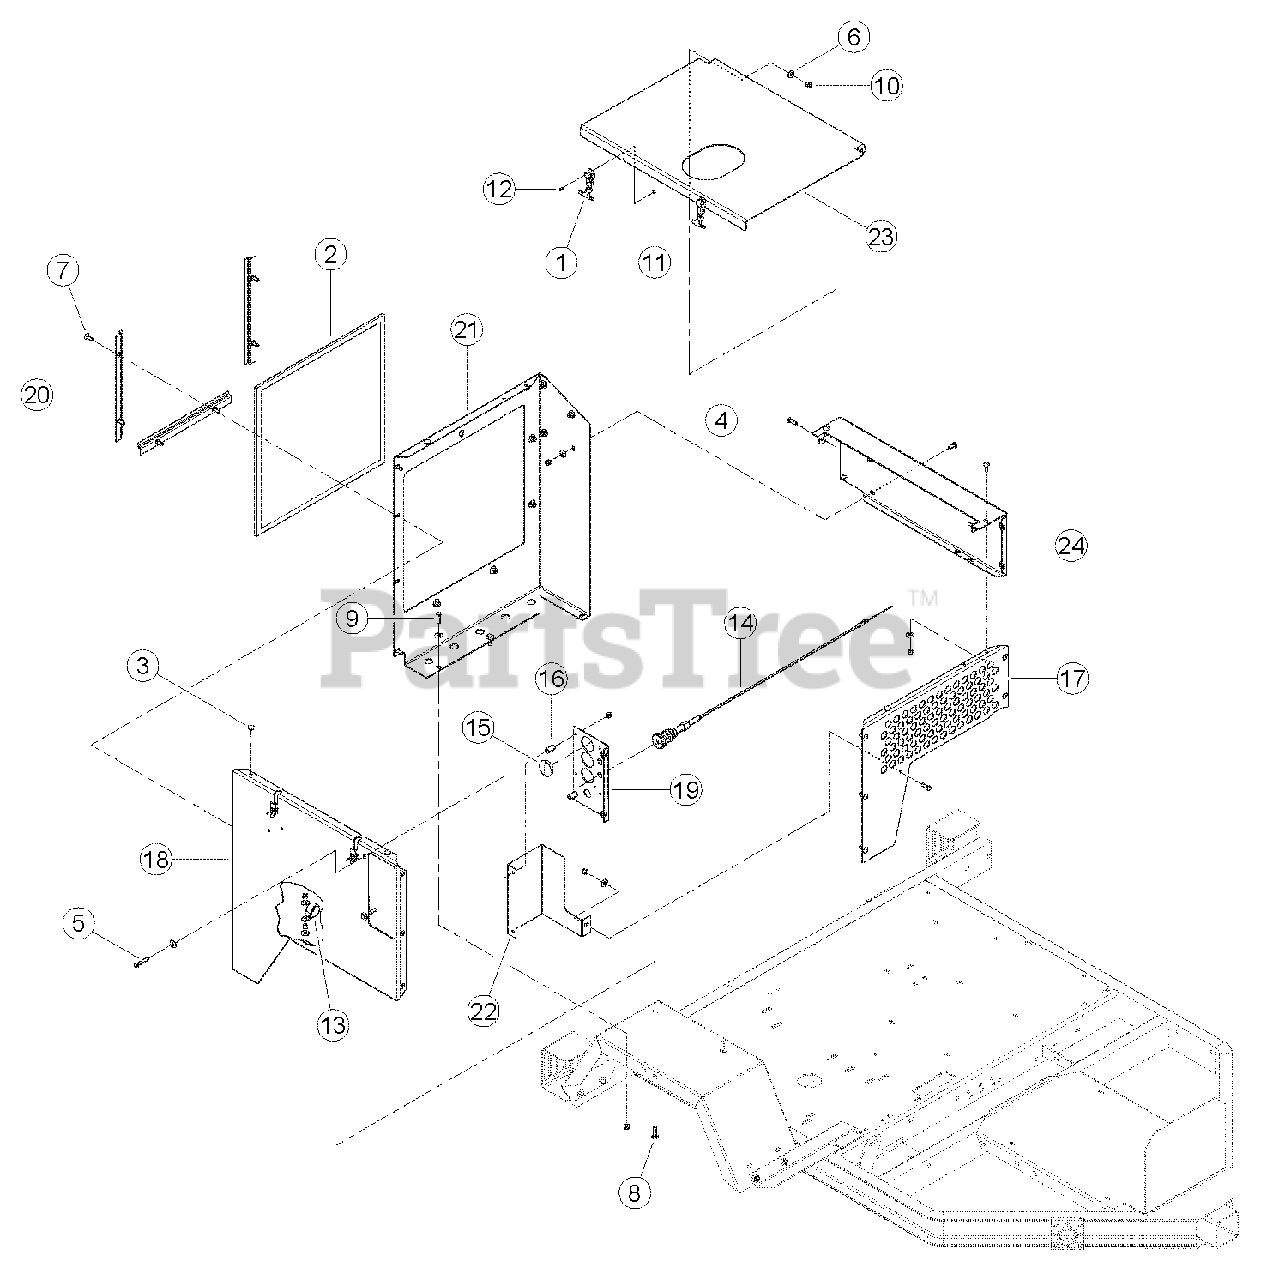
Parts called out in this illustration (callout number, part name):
1	LATCH, FLEXIBLE DRAW (2-PIECE)
2	SCREEN, RADIATOR INLET
3	BUMPER, RUBBER
4	BOLT, 3/8 X 1 HEX HD GR5 ZP
5	BOLT, 3/8 X 2 HEX HD GR5 ZP
6	WASHER, 3/8 FLAT ZP
7	BOLT, 3/8 X 1 CRG GR5 NC ZP
8	BOLT, 3/8 X 1-1/2 CRG GR5 NC ZP
9	BOLT, 3/8 X 1-1/4 HEX HD GR5 ZP
10	NUT, 3/8 NE NYLOCK ZP
11	NUT, 10/24 NYLOCK TYPE NM ZP
12	SCREW, MCH 10-24 X 1/2 PAN HD PH ZP
13	CLAMP, 1-9/16 COATED METAL
14	CABLE, DIESEL THROTTLE
15	PLUG, 2 IN. DOME
16	IDLER SPACER
17	COVER, REAR ENGINE
18	PANEL, SIDE COVER
19	PANEL, ENGINE CONTROL
20	BRACKET, SCREEN HOLDER
21	PANEL, RADIATOR COVER
22	SHIELD, 50 HP HEAT
23	HOOD, ENGINE
24	SIDE, ENGINE COVER
